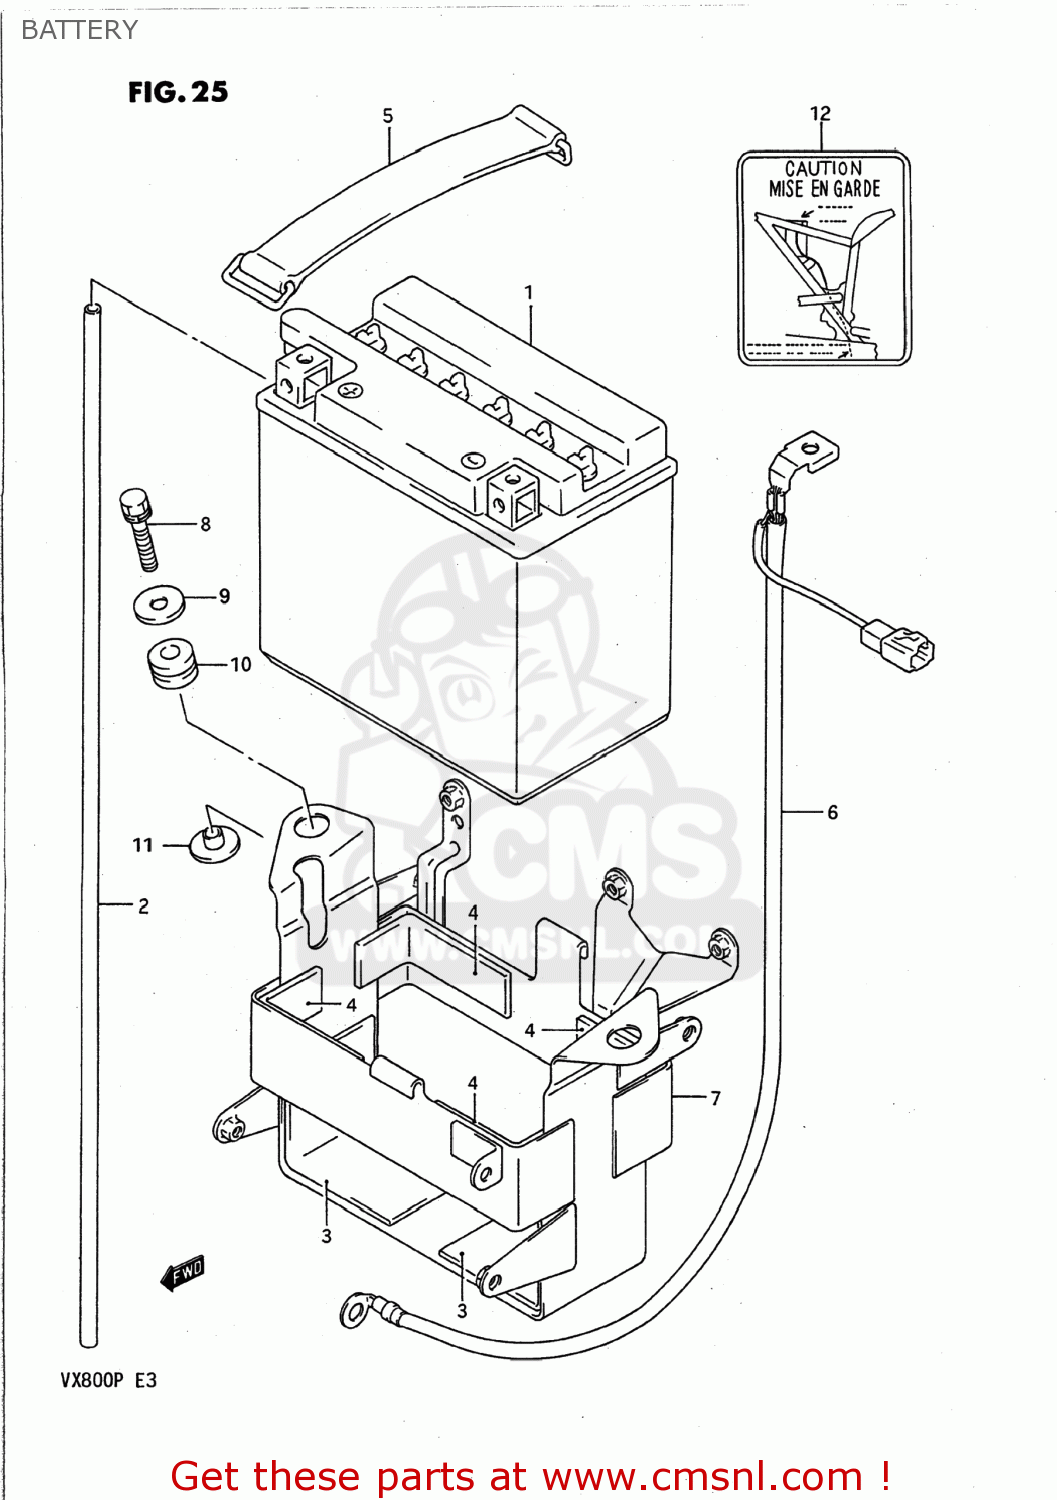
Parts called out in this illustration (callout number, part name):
1	BATTERY ASSEMBLY (12V)
2	HOSE,BATTERY EXHAUST
3	PROTECTOR(170X95X3.0)
4	PROTECTOR,20X9
5	BAND
6	WIRE,BATTERY MINUS LEAD
7	HOLDER,BATTERY
8	BOLT
9	WASHER(6,5X22X1.6)
10	CUSHION
11	PLATE,BATTERY HOLDER
12	PLATE,BATTERY CAUTION
